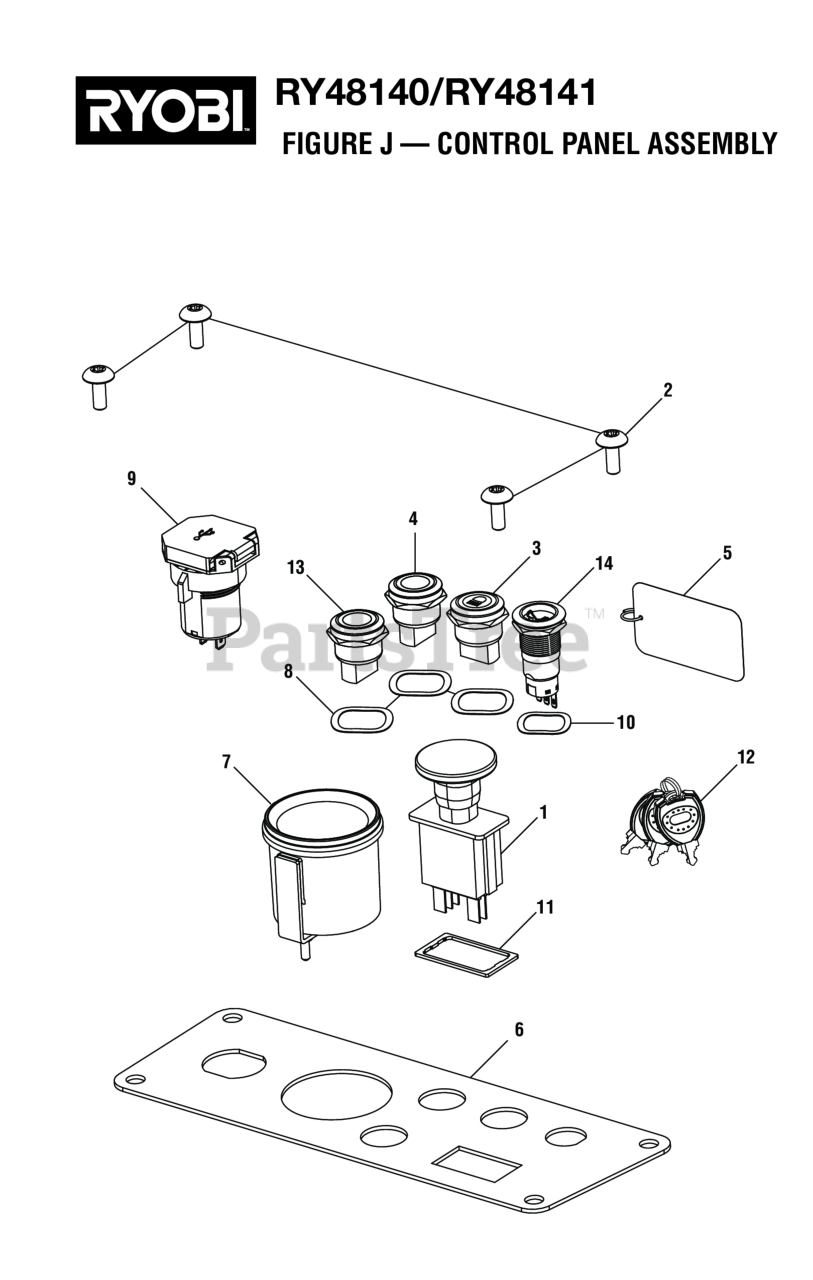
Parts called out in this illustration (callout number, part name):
1	Power Take Off Button (PTO)
2	Screw (M6 x 10 mm, Soc. Button Hd.)
3	Light Switch
4	Button Switch, Drive Speed
5	Watch For Kids, Keychain Label
6	Control Panel Face Plate
7	Fuel Gauge, ZTR
8	Wavy Washer
9	USB Module
10	Wavy Washer
11	PTO Gasket
13	Button Switch, Blade Speed
14	Switch Key Module
